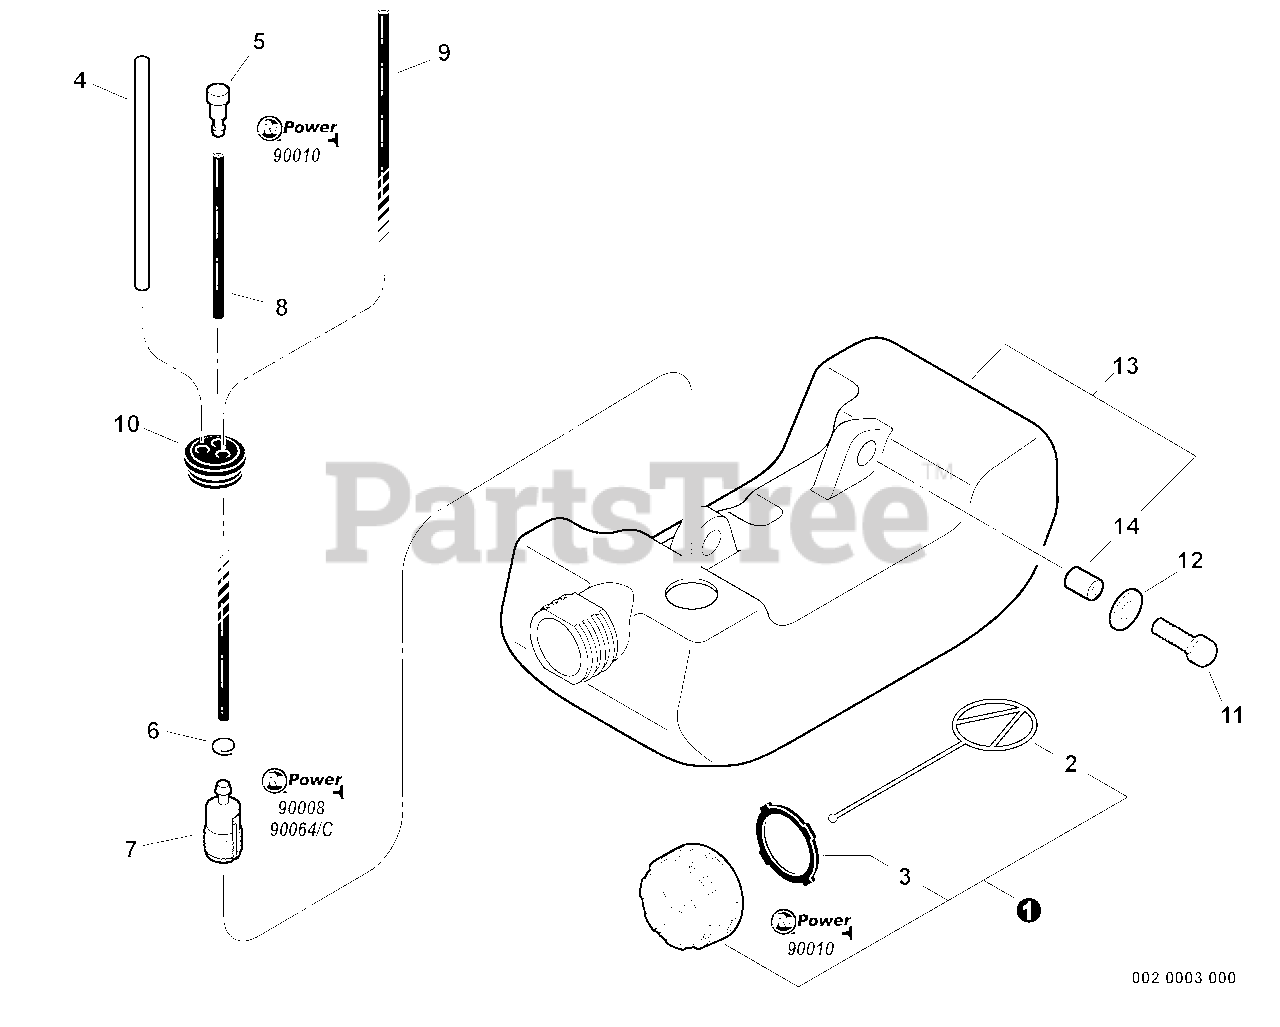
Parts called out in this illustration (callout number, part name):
1	CAP ASSY - ORANGE
2	CONNECTOR, CAP
3	GASKET, CAP
4	PIPE - 3X6X90 -- CLEAR
5	VENT, FUEL TANK
6	CLIP - 6
7	FILTER, FUEL
8	PIPE - 3X5X70 -- BLACK
9	PIPE - 3X5X180 -- BLACK
10	GROMMET
11	SCREW - 5X16
12	WASHER - 5
13	FUEL TANK ASSY
15	RePower FILTER KIT
16	Repower CAP AND VENT KIT
17	RePower TUNE-UP KIT
